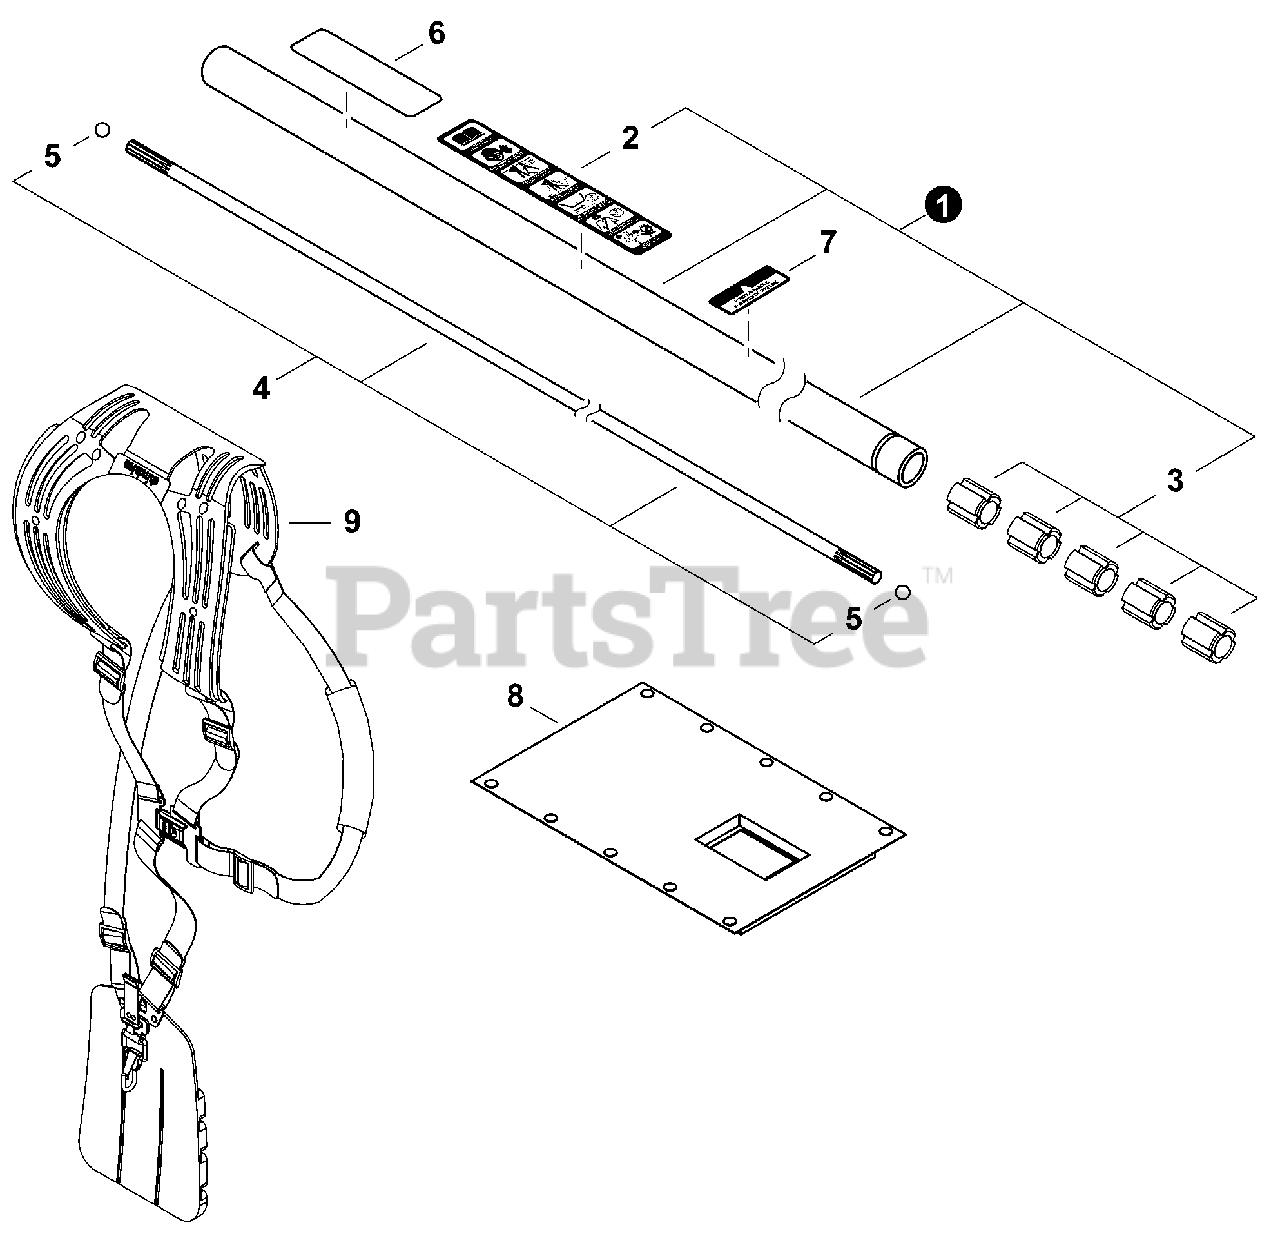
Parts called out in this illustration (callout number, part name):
1	MAIN PIPE ASSY
2	LABEL - CAUTION (BLADE CAPABLE)
3	BUSHING
4	DRIVESHAFT ASSY
5	STOPPER
6	LABEL - SHINDAIWA PROFESSIONAL
7	LABEL - HANDLE
8	PROTECTOR
9	HARNESS ASSY
